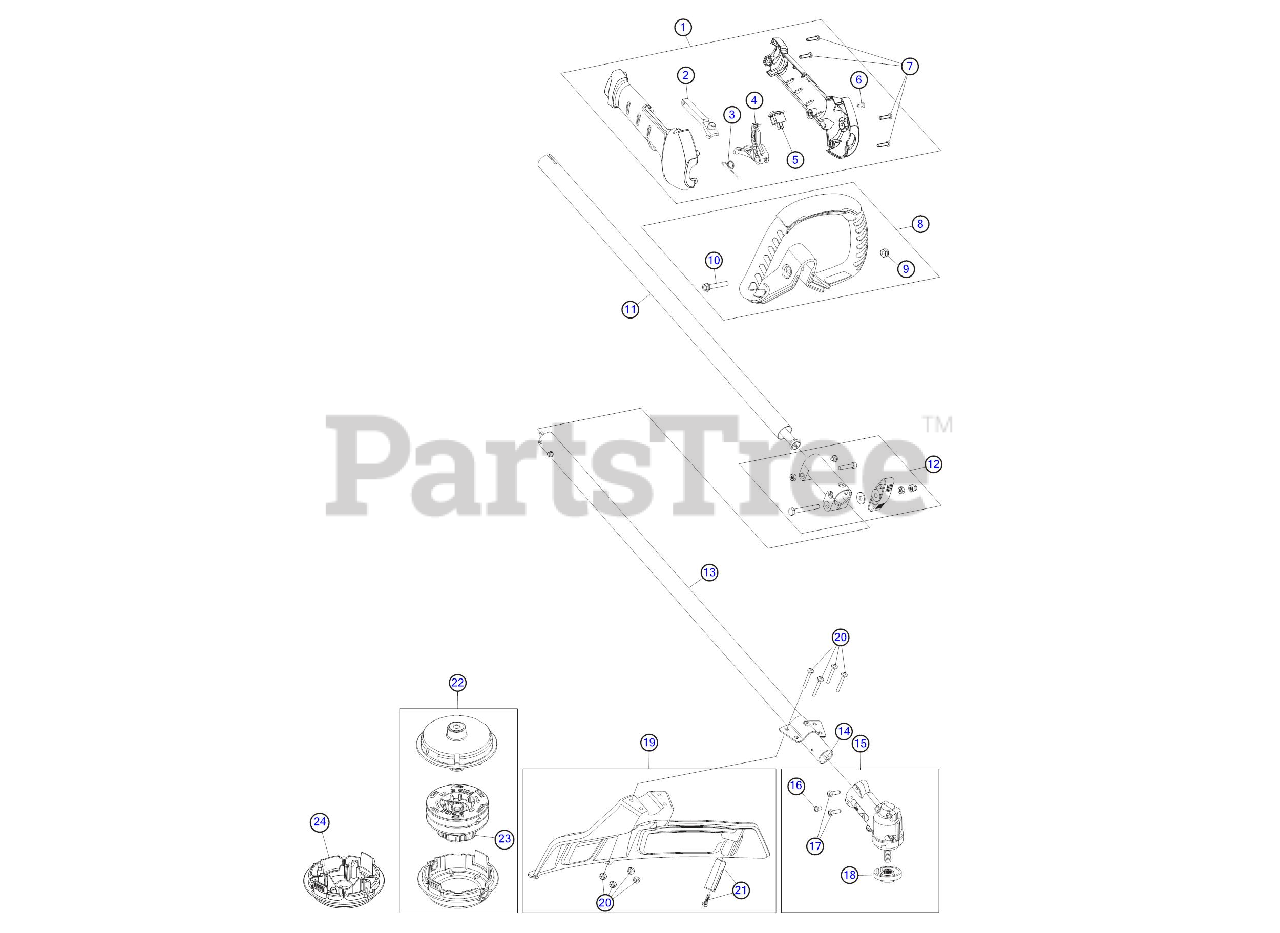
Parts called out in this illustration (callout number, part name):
1	Throttle Housing Assembly
2	Throttle Lockout
3	Throttle Trigger Spring
4	Throttle Trigger
5	Switch Assembly
6	Grip Anti-Rotation Screw
8	D-Handle Assembly
9	Nut
11	Upper Drive Shaft Housing
12	Split Boom Coupler
13	Lower Drive Shaft Housing Assembly
14	Lower Flexible Drive Shaft
15	Gearbox Assembly
16	Anti-Rotation Screw
17	Gearbox Mounting Hardware
18	Cutting Head Driver
19	Shield Assembly
20	Shield Mounting Screws and Nuts
21	Blade Assembly
22	Cutting Head Assembly
24	Cap Assembly (with Plug)
